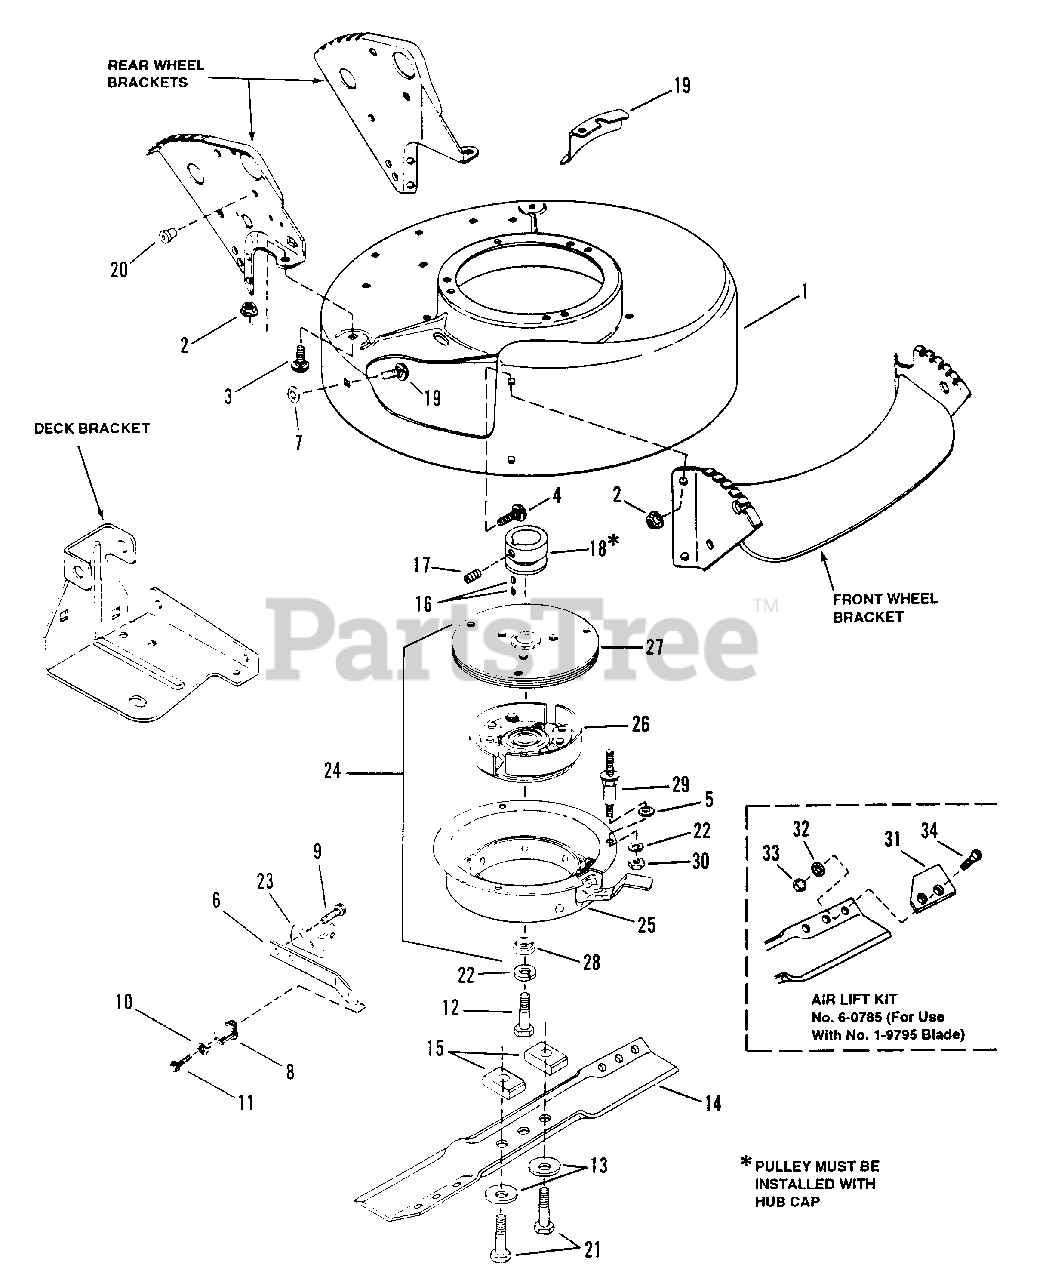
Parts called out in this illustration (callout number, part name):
1	DECK, Mower
2	NUT, Hex Flanged Lock
3	BOLT, 5/16-18 x 1/2" Short Neck Carriage Gr. 5
4	BOLT, Bolt 5/16-18 x 1-1/8" Short Neck Carriage
5	WASHER, 3/8" Flat
6	SPRING, Wheel Bracket Type Interlock
7	RETAINER, 5/16 Bolt
8	INSULATOR, Interlock
9	SCREW, 1/4-20x1/2" Hex Self-tapping
10	WASHER, No. 8 Tab Int. Tooth Lock
11	SCREW, #8-18 x 3/4" Hex Head Machine
12	SCREW, 3/8-24 x 2.0" Hex Head Cap
13	WASHER, Cone
14	BLADE, Cutter
15	SPACER, Blade
16	KEY, Hi-Pro
17	SCREW, 5/16-18 x 5/16" Hex Socket Set
18	PULLEY, Engine (25mm I.D. x 2-1/8" O.D.)
19	BOLT, 5/16-18 x 3/4" Short Neck Carriage
20	BUSHING, Interlock Wire
21	SCREW, 3/8-16 x 1-3/4" Hex Head Cap
22	LOCKWASHER, 3/8 Split
23	BRACKET, CABLE-BBC
24	ASSEMBLY, Blade Clutch
25	ASSEMBLY, Bowl & Brake
26	ASSEMBLY, Clutch Bearing
27	ASSEMBLY, Flywheel
28	WASHER, Blade
29	STAND-OFF (Engine Mounting)
30	NUT, 3/8-16 Hex Flange Lock
31	LIFT, Air
32	WASHER, 5/16 Internal Tooth Lock
33	NUT, 5/16-24 Hex
34	SCREW, 5/16-24 x 21/32" Machine
